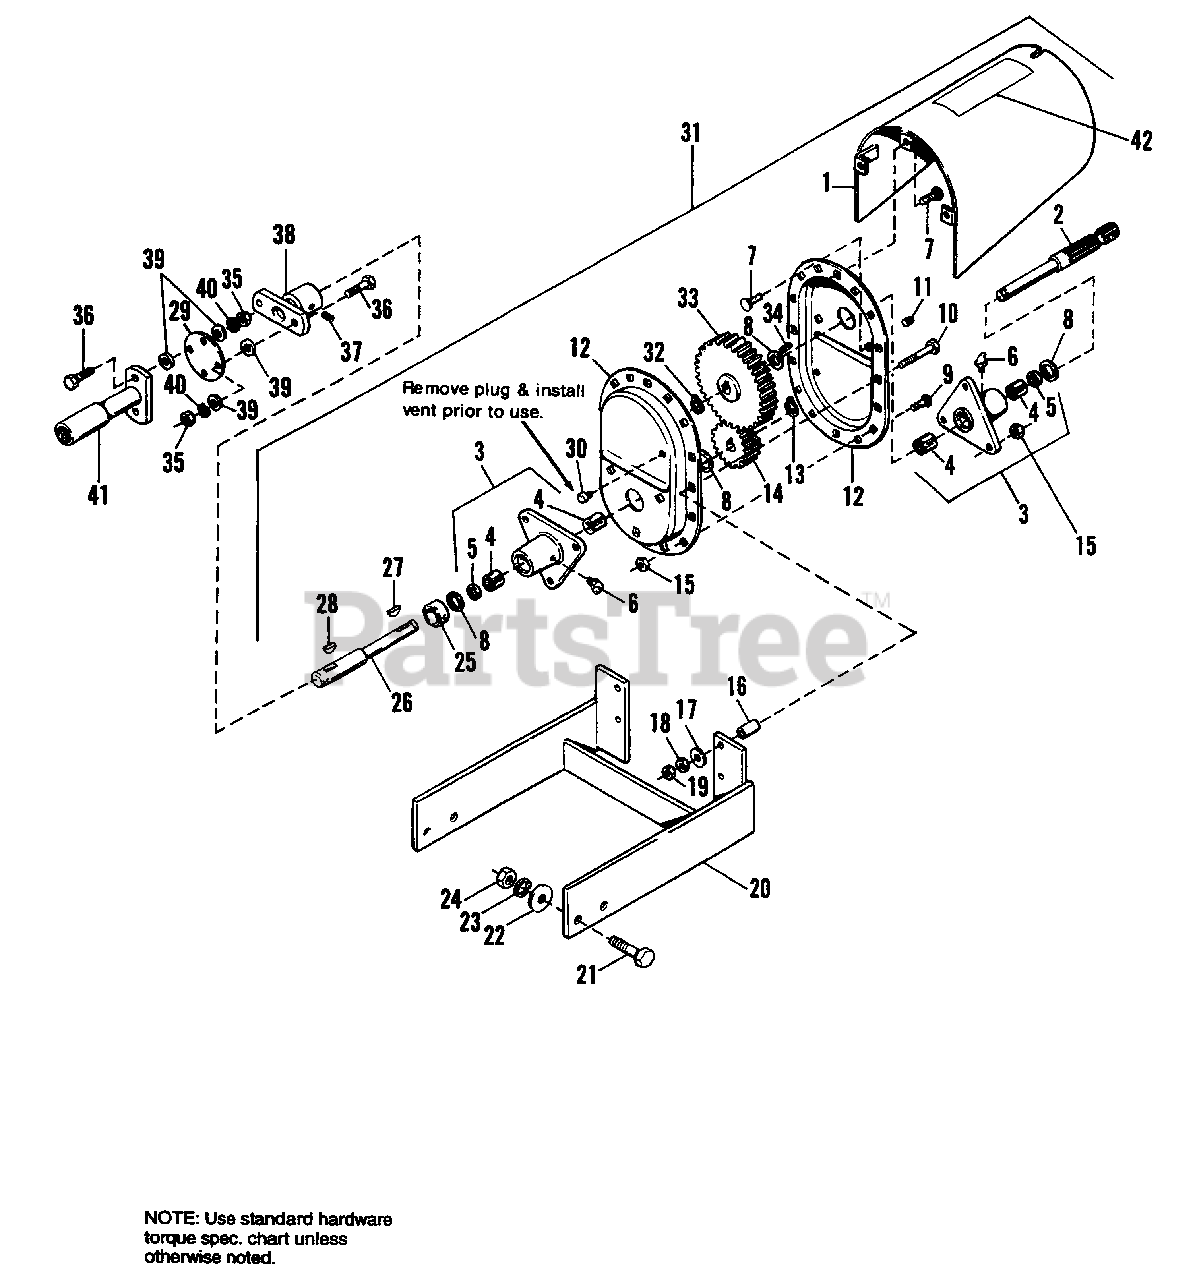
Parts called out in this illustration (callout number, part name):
1	SHIELD ASSY., P.T.O.
2	SHAFT, Output
3	HUB ASSY., w/Bearings & Seal
4	BEARING, Needle
6	FITTING, Grease
7	CARRIAGE BOLT, 5/16 x 1
8	WASHER, Thrust
9	CARRIAGE BOLT, 5/16 x 3/4
10	CAPSCREW, Hex Hd., 5/16-18 x 2-1/2
12	COVER, Gear Box (Half)
13	RING, Retainer
14	GEAR, Pinion, 18 Teeth
15	NUT, Hex Lock, 5/16-18
18	NUT, Hex, 5/16-18
19	NUT, Hex, Jam, 5/16-18
20	CARRIER ASSY.
21	CAPSCREW, Hex Hd., 5/8-11 x 2
22	WASHER, 5/8
23	LOCKWASHER, 5/8
24	NUT, Hex, 5/8-11
25	COLLAR, Bearing
26	SHAFT, Input
27	KEY, Woodruff
28	KEY, Woodruff
31	HOUSING ASSY., Reduction w/Shield
32	RING, Retaining
33	GEAR, Driven, 72 Teeth
34	KEY, Parallel
35	NUT, Hex, 5/16-18
36	CAPSCREW, Hex Hd., 5/16-16 x 1-1/4
37	SETSCREW, 5/16-18 x 1/2
38	COUPLER ASSY.
39	WASHER, Special
40	LOCKWASHER, 5/16
41	SHAFT ASSY., 540 P.T.O.
42	DECAL, Warning
